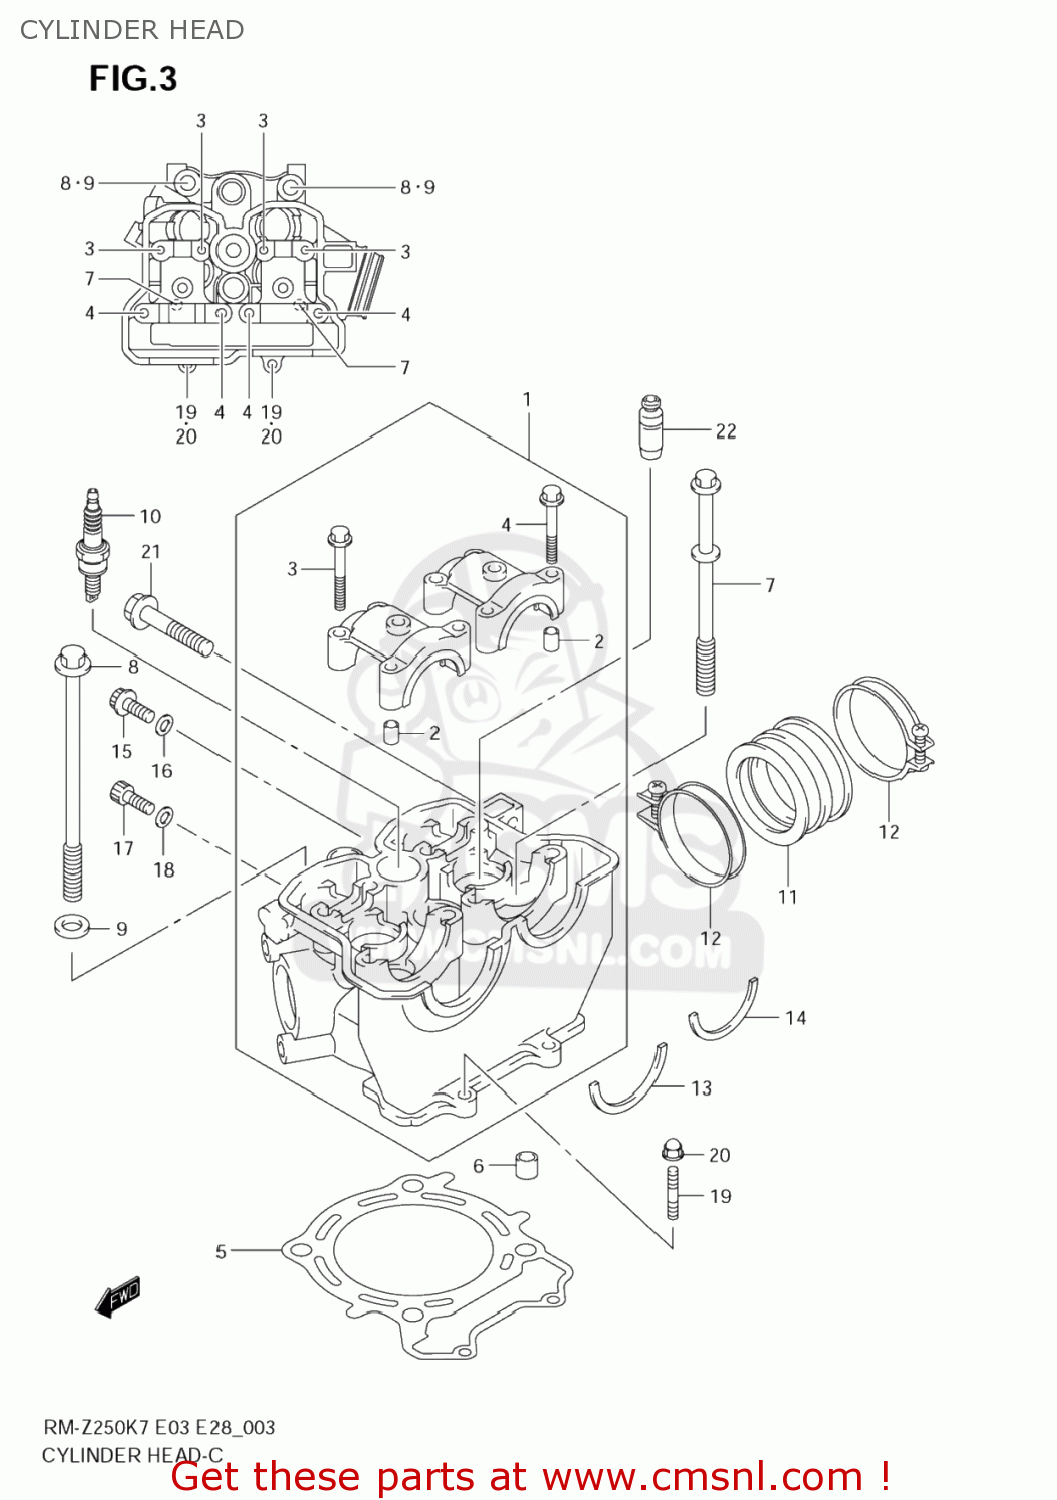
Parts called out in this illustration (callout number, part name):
1	HEAD ASSY,CYLINDER
2	PIN(6.2X8X11)
3	BOLT
4	BOLT
5	GASKET,CYLINDER HEAD (NAS)
6	PIN
7	BOLT,CYLINDER HEAD
8	BOLT(10X124)
9	GASKET(10.2X20X2).3 (NAS)
10	PLUG,SPARK(CR8EIA-10)
11	PIPE,INTAKE
12	CLAMP,INTAKE PIPE
13	C RING,CAMSHAFT
14	C RING,CAMSHAF
15	BOLT
16	GASKET(6.2X11X1).2 (NAS)
17	BOLT
18	GASKET(8.2X14X1).6 (NAS)
19	BOLT,STUD
20	NUT
21	BOLT(10X50)
22	GUIDE,VALVE(OS:0.3)
